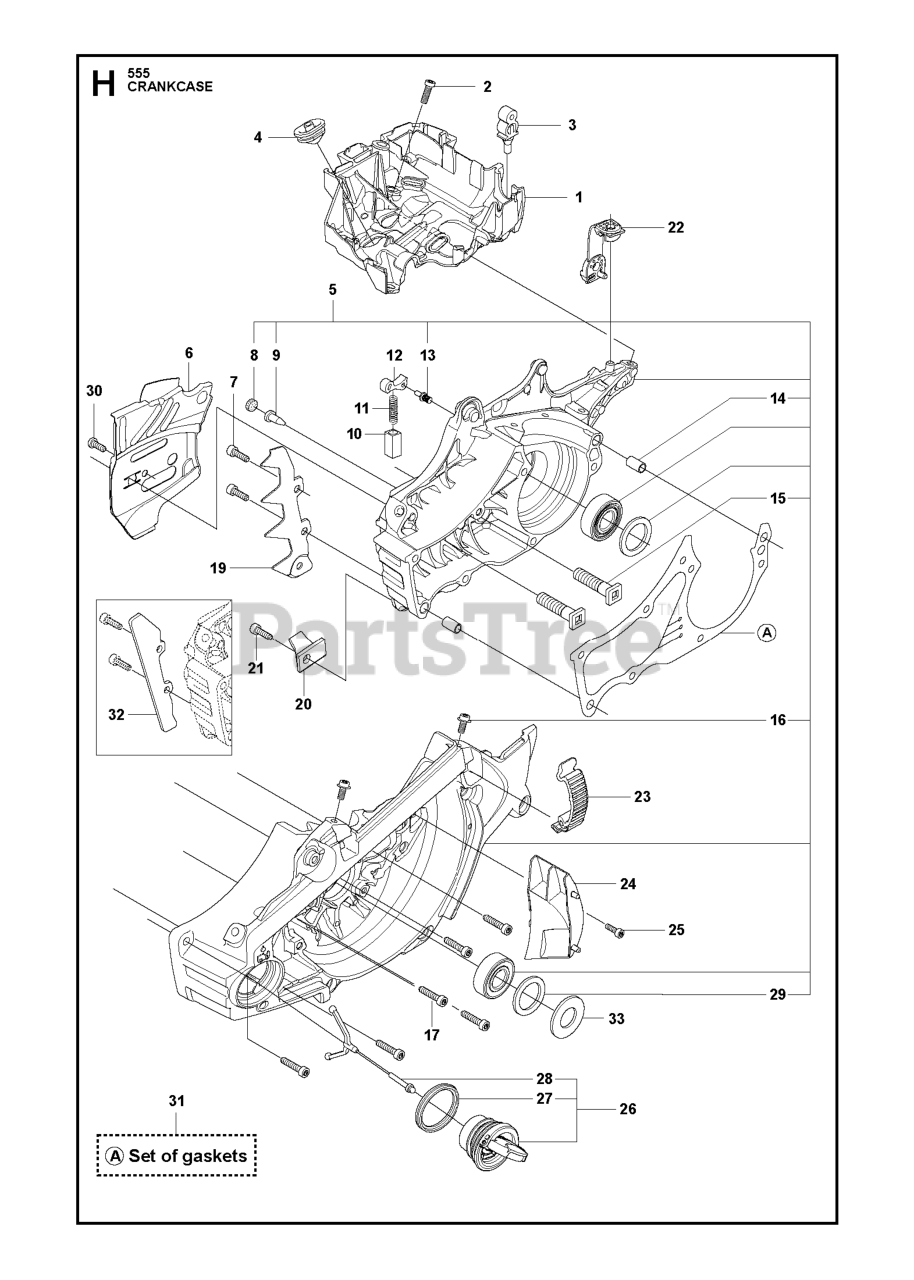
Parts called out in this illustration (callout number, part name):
1	Carburetor base
2	SCREW ITXSCFM
5	CRANKCASES
6	CHAIN GUIDE PLATE
7	SCREW ITXPANM M5X16 T27 10.9
8	PLUG
9	VALVE-CHECK (DUCKBILL)
11	LOCK SPRING
14	GUIDE BUSHING
16	SCREW ITXSCM WASHER M5X12 T27
17	SCREW ITXSCM M5X25 12.9 TBO T
20	CHAIN CATCHER
22	DEFLECTION LIMITER
23	CLIP GRAY
24	AIR NOZZLE
25	SCREW ITXSCM M4X15 T27 12.9 T
26	TANK CAP ASSY
29	RADIAL SEAL
30	SCREW CITXPANT
31	GASKET KIT
32	RP ENCLOSED KIT
33	CAPS
